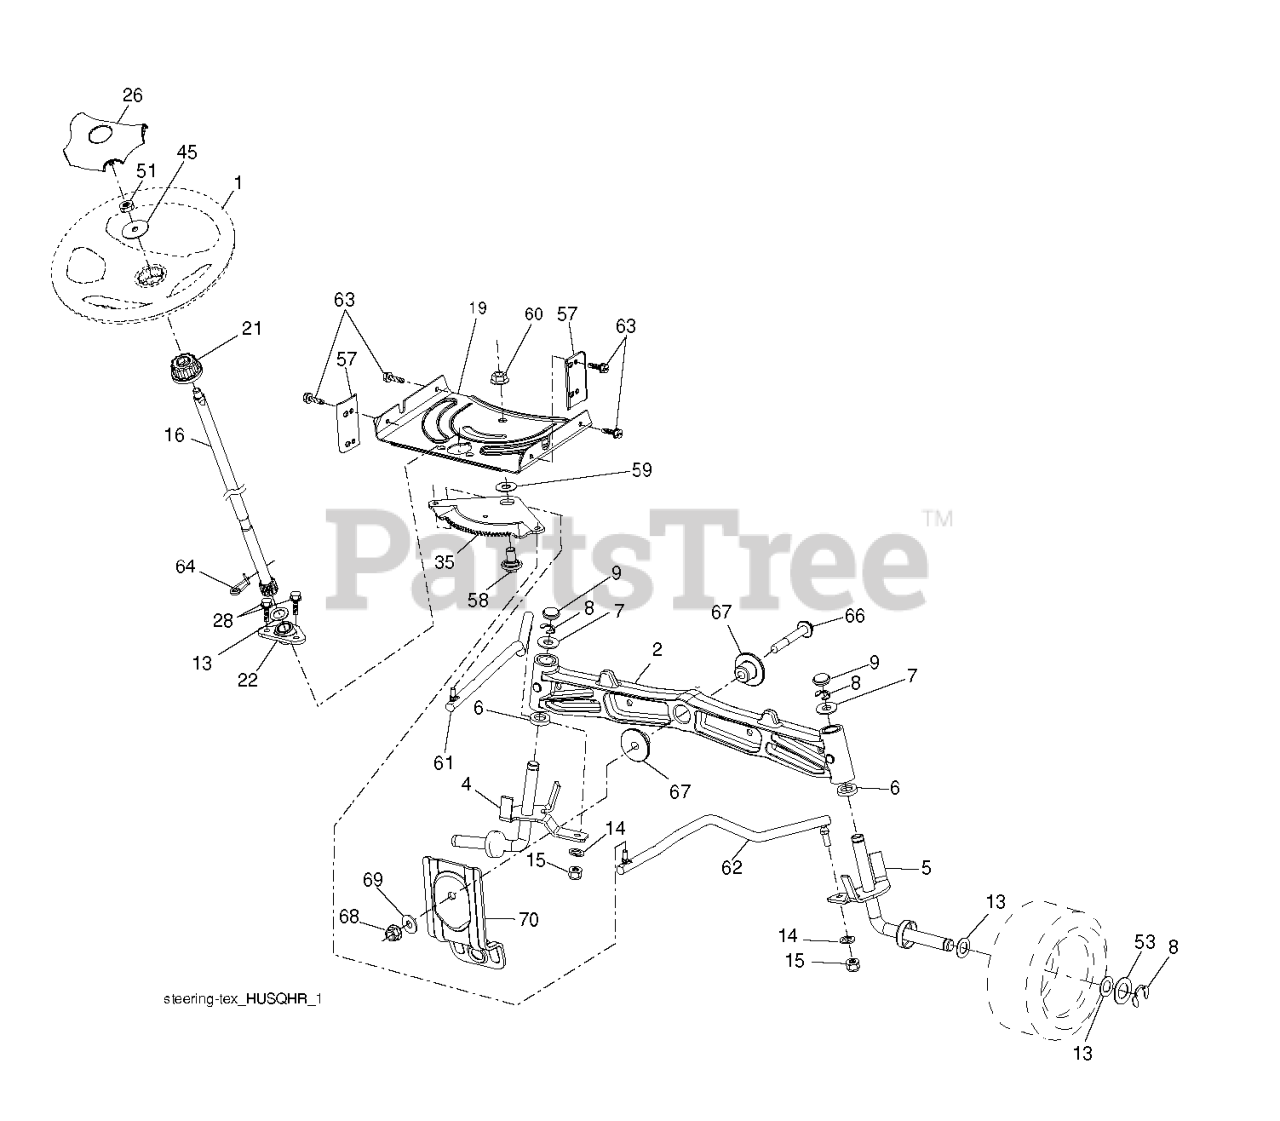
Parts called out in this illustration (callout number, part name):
1	RP WHEEL.STEER.HUSQ.PREM.OVMLD
2	AXLE.SVC.ASM CAST IRON.TEX
4	SPINDLE.WELDED.LH.15"TEX
5	SPINDLE.WELDED.RH.15"T
6	THRUST WASHER
9	CAP.SPINDLE.BLACK
14	WASHER, LOCK 3/8
15	NUT CROWNLOCK 3/8-24
16	SHAFT.STEER.STEALTH.DD
19	PLATE.STEER.DDL.NLT/NG
21	ADAPTER, WHEEL STNG..
22	STEERING.SUPT.LOWER.
26	RP INSERT.CAP.WHL.STRG.HUSQ.
28	SCREW, 3/8-16X3/4
35	GEAR.SECTOR.PLATE.DDL.
45	WASHER 9/16"ID, 2 3/8"OD
51	NUT.HEX.1/2-20
53	WASHER.HARDENED
57	BRACKET.UPSTOP.TEX
58	BOLT.SHOULDER.SECTOR.P
59	WASHER.THURST.SECTOR.S
60	NUT FLANGE LOCK 5/8-11
61	DRAGLINK.LH.BALLSTUD.D
62	DRAGLINK.RH.BALLSTUD.D
63	SCREW
64	RETAINER.CLIP.SPRING.S
66	BOLT HEX FGHD 7/16-14 X 3 SERR
67	BUSHING.PM.FRONT AXLE
68	NUT.LOCK.FLANGE.7/16
69	WASHER.1.5X.505X.118
70	BRKT.DECK.SUSPENSION.F
118	BUSHING, AXLE CAST
